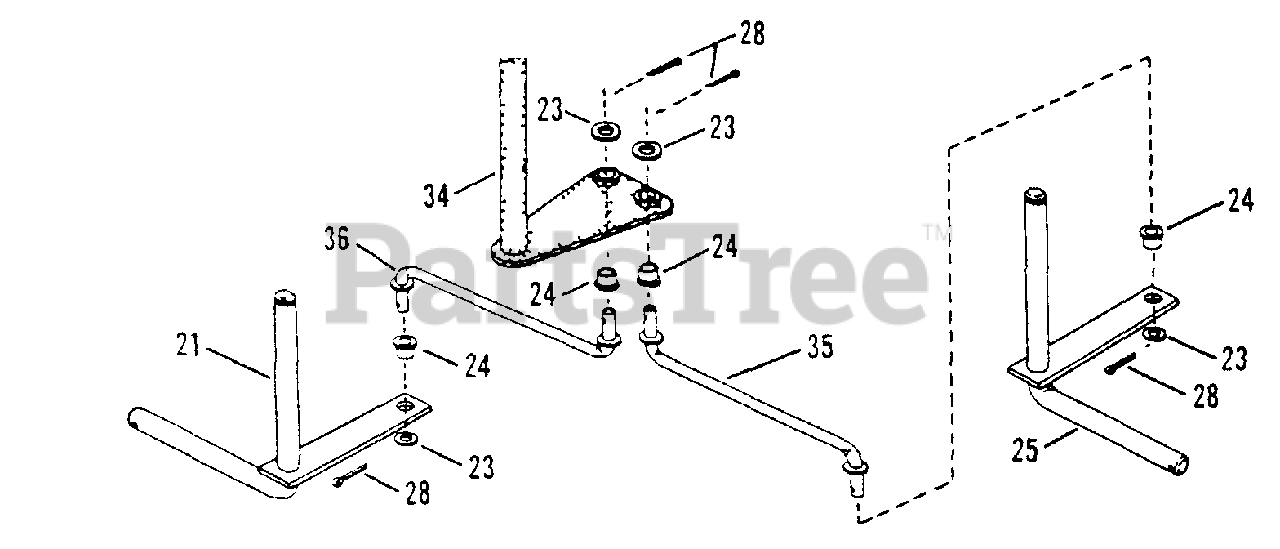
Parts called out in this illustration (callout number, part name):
21	PIN, Narrow King (Right Side)
23	WASHER, 5/16 Split Lock
24	BUSHING
25	PIN, Narrow King (Left Side)
28	PIN, 5/32 x 1" Cotter
34	SHAFT, Steering
35	TIE-ROD, Left Side
36	TIE-ROD, Right Side
